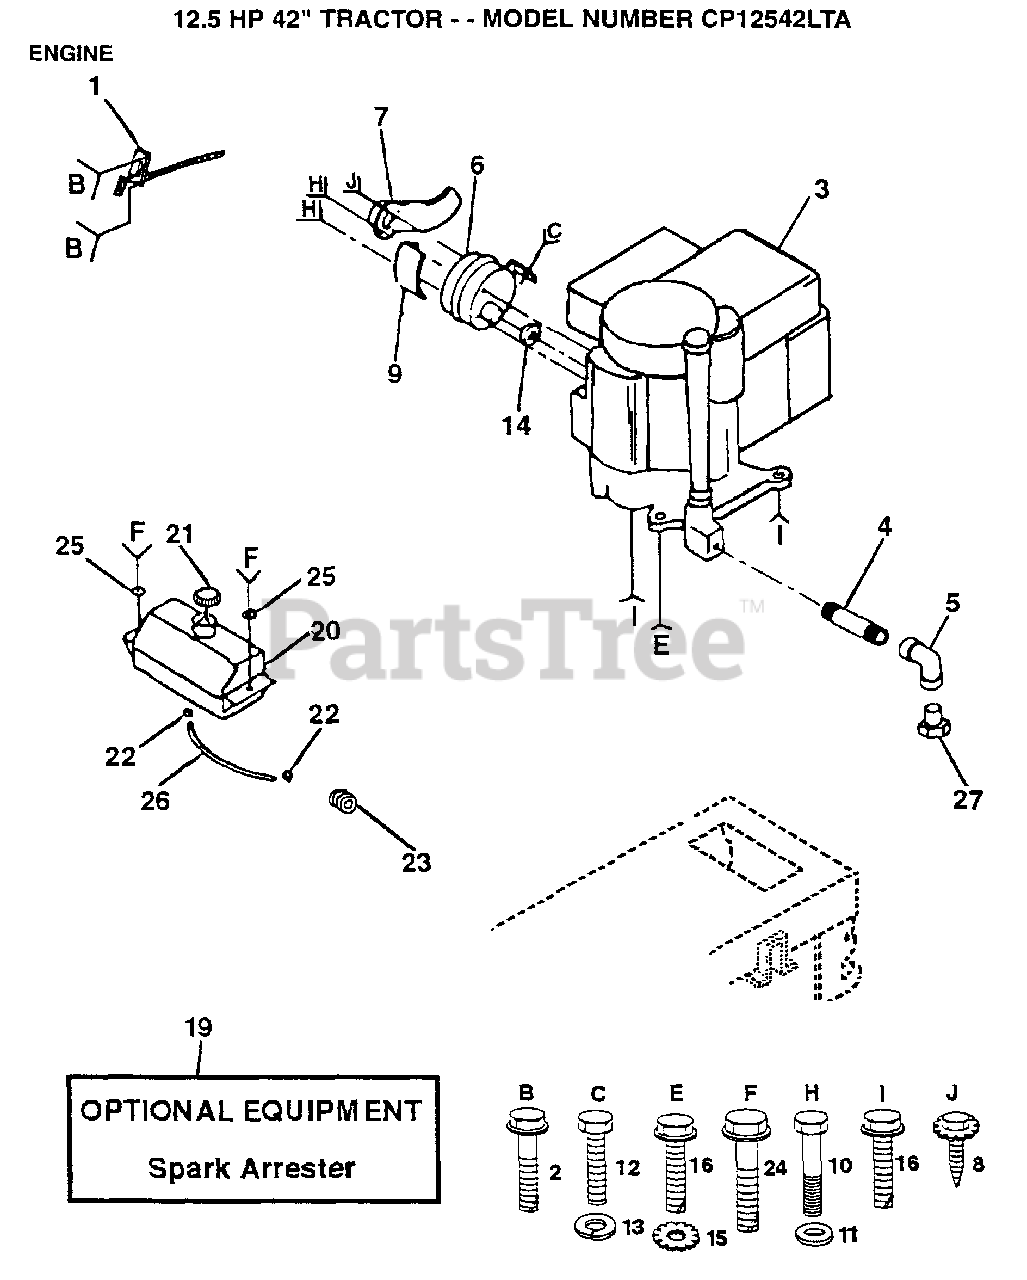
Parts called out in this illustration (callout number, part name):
1	THROTTLE CONTROL
2	SCREW LT
3	ENG. B&S12.5 HP
4	PIPE NIPPLE
5	ELBOW
6	MUFFLER EXHUST
7	DEFLECTOR MUFFLER
9	SHIELD HEAT LTV
10	"BOLT,HEX"
11	WASHER T
12	BOLT
13	LOCKWASHER
15	LOCKWASHER
16	SCREW
20	TANK.FUEL.LT.
21	CAP ASM FUEL
22	HOSE CLAMP
24	SCREW HEX CRT
25	WASHER
26	LINE FUEL
